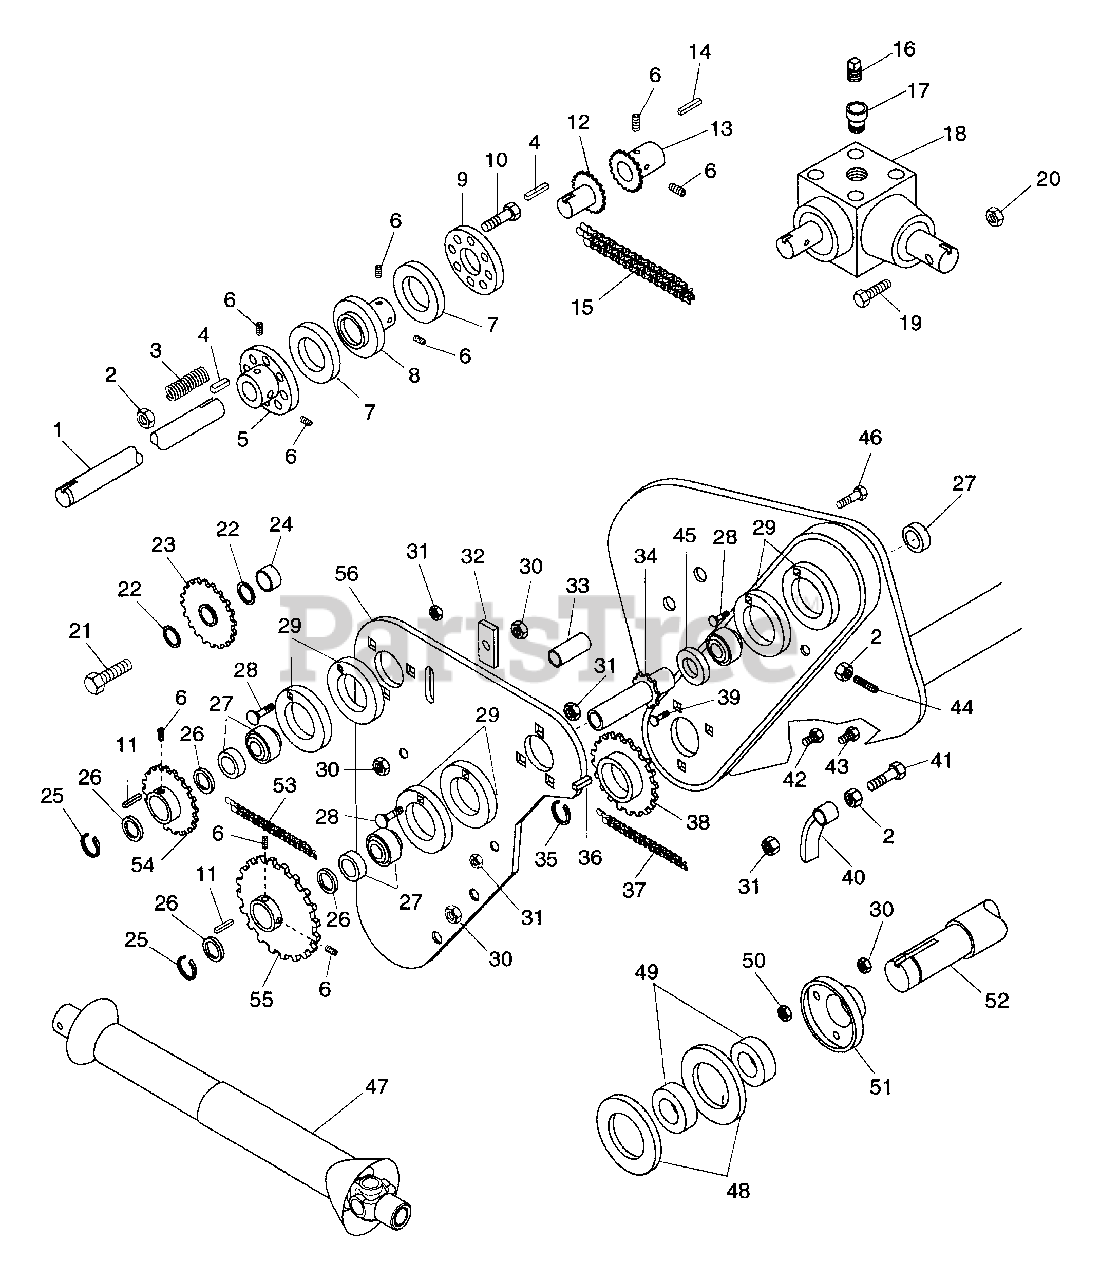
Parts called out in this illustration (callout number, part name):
1	DRIVE SHAFT
2	NUT-HEX .312-18
3	SG-COMP .135X.66X.75 WLD210
4	KEY-SQ .25 X 1.25 X .25 SAE
5	HUB-END PLATE
6	SCR-SET .32-18X.50 SKH
7	CLUTCH DISC
8	HUB-CENTER
9	PRESSURE PLATE
10	BLT-HEX .31-18X2.75 GR5
11	KEY-SQ .25X1.0X.25 SAE 8630
12	COUPLER-MALE HALF
13	COUPLER-FEMALE HALF
14	KEY-SQ .25 X 1.50 X .25 SAE
15	CHAIN-COUPLER
16	VENT PLUG
17	COUPLING
18	GEAR BOX ASSEMBLY
19	BLT-HEX .38-16X2.50 PL GR5
20	NUT-LK TOP .375-16 GR C YWZC
21	BLT-HEX .50-13X2.75 PL GR5
22	WSHR-FL-STL .505X1.000X.062
23	IDLER SPROCKET
24	SPACER-IDLER
25	RG-RTNG-EXT 1.00X.042
26	WSHR-FL-STL 1.015X1.500X.134
27	BRG-BALL 1.0X2.047X.59
28	BLT-RDHDSQNK.31-18X.75GR5SHTPL
29	FLANGETTE
30	NUT-LK-CROWN .50-13 GR C PL
31	NUT-LK-TOP .312-18 GR C PL
33	TUBE .512 X .747 X 2.00
34	SPROCKET SHAFT
35	RG-RTNG-EXT 1.500X.050
36	KEY-SQ .38X1.00X.375 SAE 1035
37	DRIVE CHAIN
38	DRIVEN SPROCKET
39	BLT-RDHDSQNK .50-13X1.50 PL
40	CHAIN TIGHTNER
41	BLT-HEX .31-18X2.75 GR2
42	CARRIAGE BOLT-SPECIAL
43	BLT-RDHDSQNK .38-16X2.25 SHTPL
44	SCR-SET .32-18X2.00 SKHCUP
45	SPACER 1.050X1.312X.410
46	BLT-HEX .50-13X3.00 PL GR2
47	UNIVERSAL DRIVE SHAFT
48	FLANGETTE-4 HOLE
49	BRG-BALL 1.50X80MMX1.7
50	NUT .50-13 PL
51	CAP-BEARING GUARD
52	TINE SHAFT
53	ROLLER CHAIN
54	SPROCKET 11T
55	SPROCKET 40 T
56	INNER COVER
